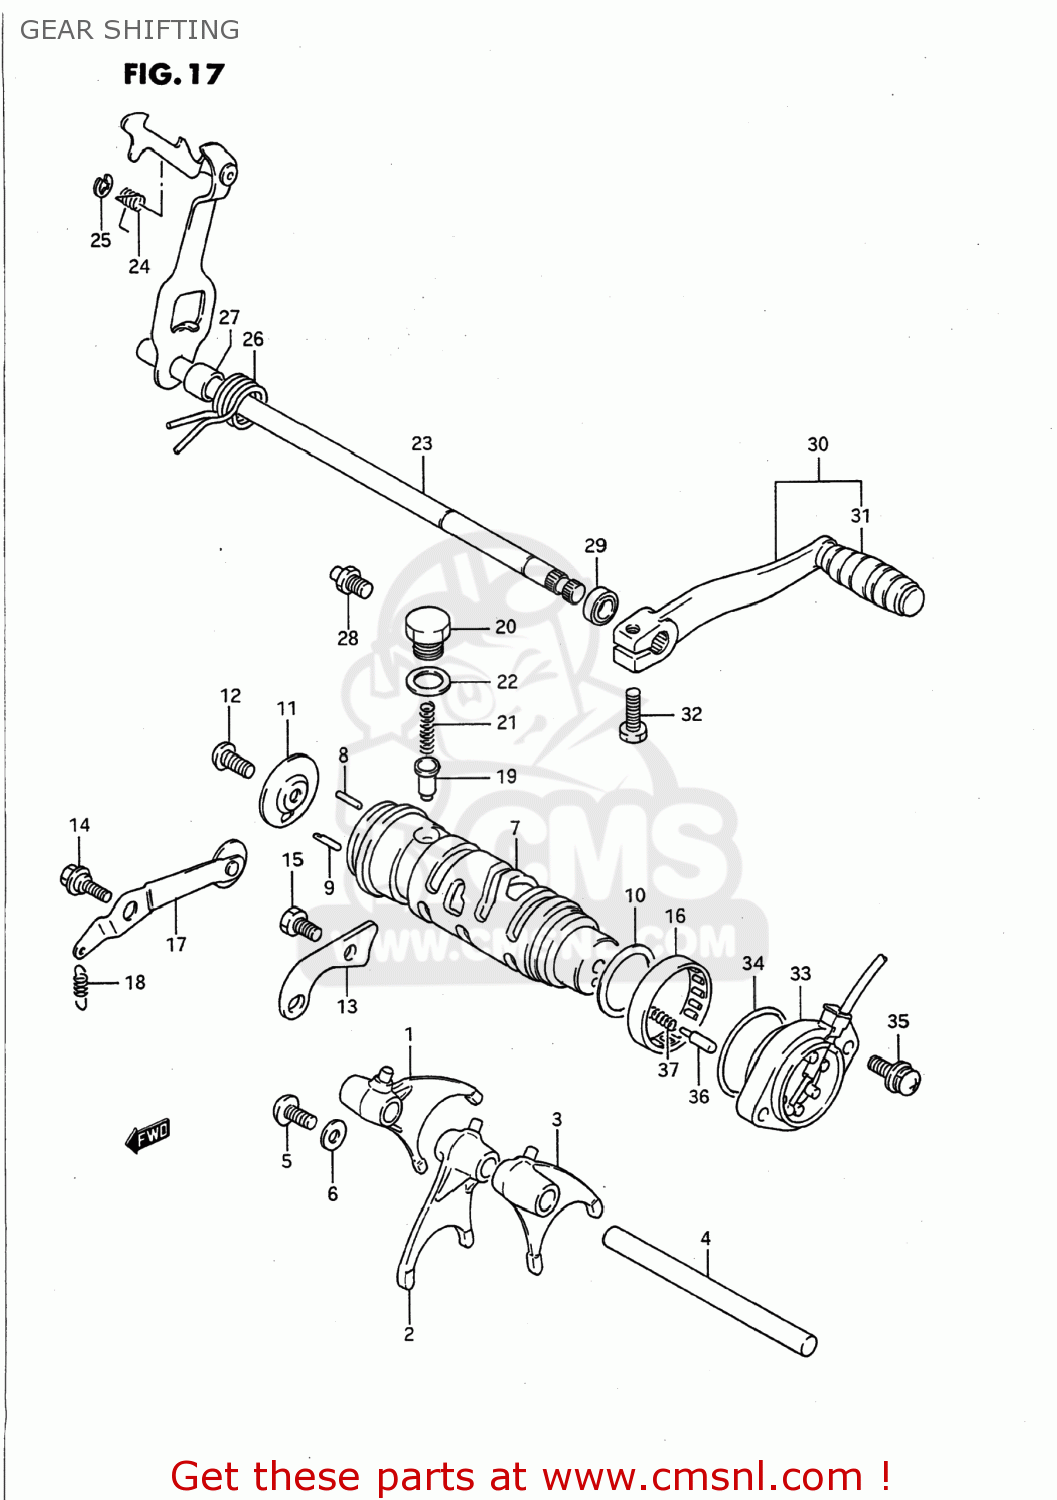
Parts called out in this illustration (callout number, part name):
1	FORK,GEAR SHIFT NO.1
2	FORK,GEAR SHIFT NO.2
3	FORK,GEAR SHIFT NO.2
4	SHAFT,GEAR SHIFT FORK
5	SCREW
6	WASHER
7	CAM,GEAR SHIFT
8	PIN(4X18.5)
9	PIN
10	SHIM(26X32.5X0.3)
11	RETAINER,GEAR SHIFT CAM DR PIN
12	SCREW
13	GUIDE,GEAR SHIFT CAM
14	BOLT
15	BOLT
16	BEARING(40X47X12)
17	STOPPER,GEAR SHIFT CAM NO.1
18	SPRING
19	STOPPER,GEAR SHIFT CAM NO.2
20	HOLDER,GEAR SHIFT CAM STOP SPR
21	SPRING
22	GASKET(14X19.2X2) (NAS)
23	SHAFT,GEAR SHIFT
24	SPRING
25	E RING
26	SPRING
27	SPACER(12X20X15.3)
28	STOPPER,GEAR SHIFT CAM
29	OIL SEAL
30	LEVER ASSY,GEAR SHIFT
31	RUBBER,GEAR SHIFT PEDAL
32	BOLT
33	BASE ASSY,NEUTRAL SW TERMINAL
34	O-RING (D:2.4 ID:26.2)
35	SCREW
36	PIN(5X15.5)
37	SPRING
